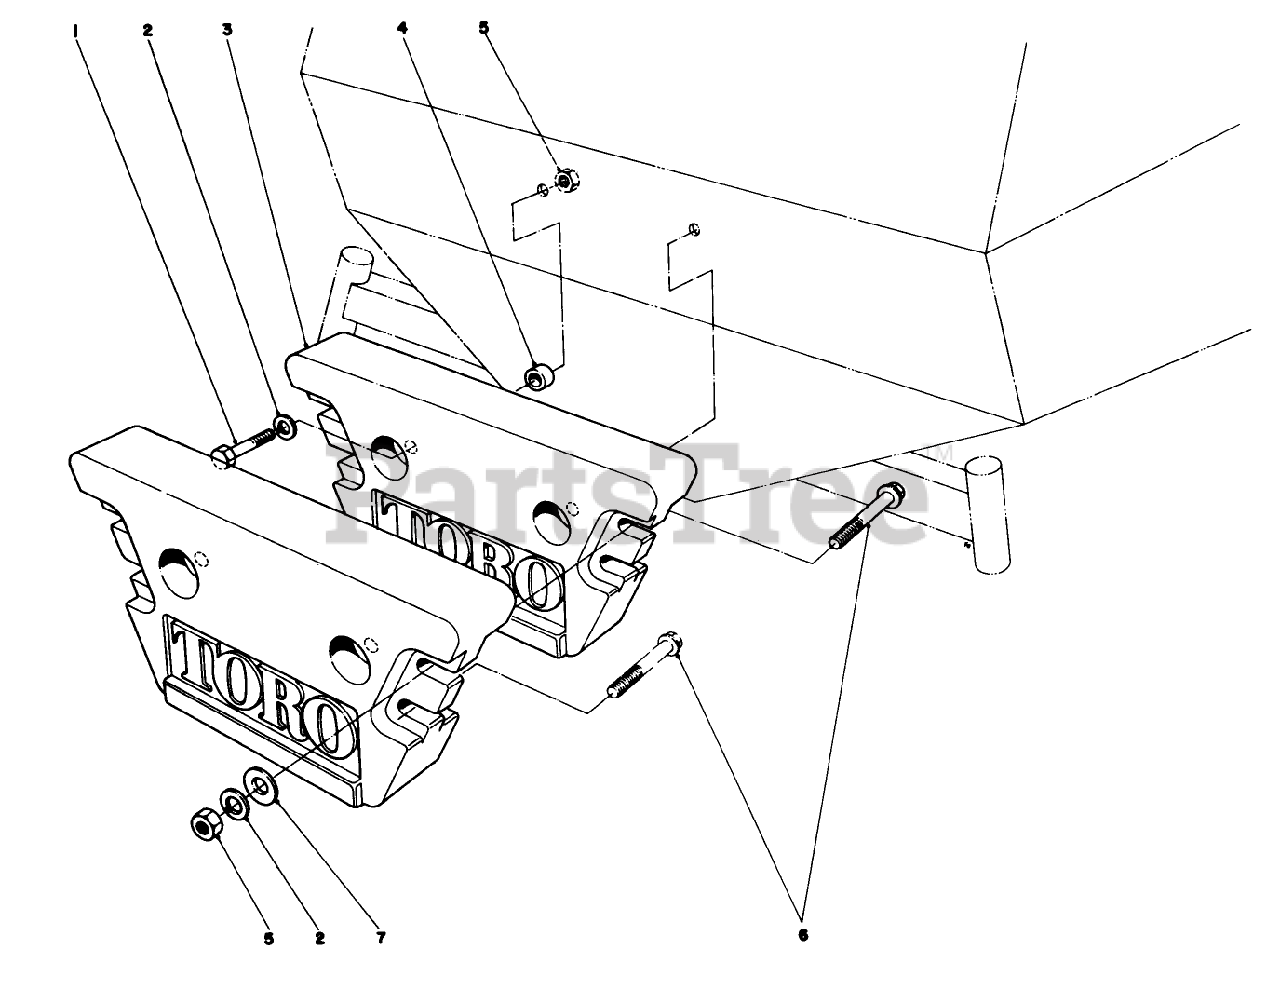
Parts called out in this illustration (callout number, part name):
1	SCREW-HH
2	SCREW-HH
4	SPACER-TUBULAR
5	NUT-HH
6	SCREW-HH
7	WASHER-FLAT
